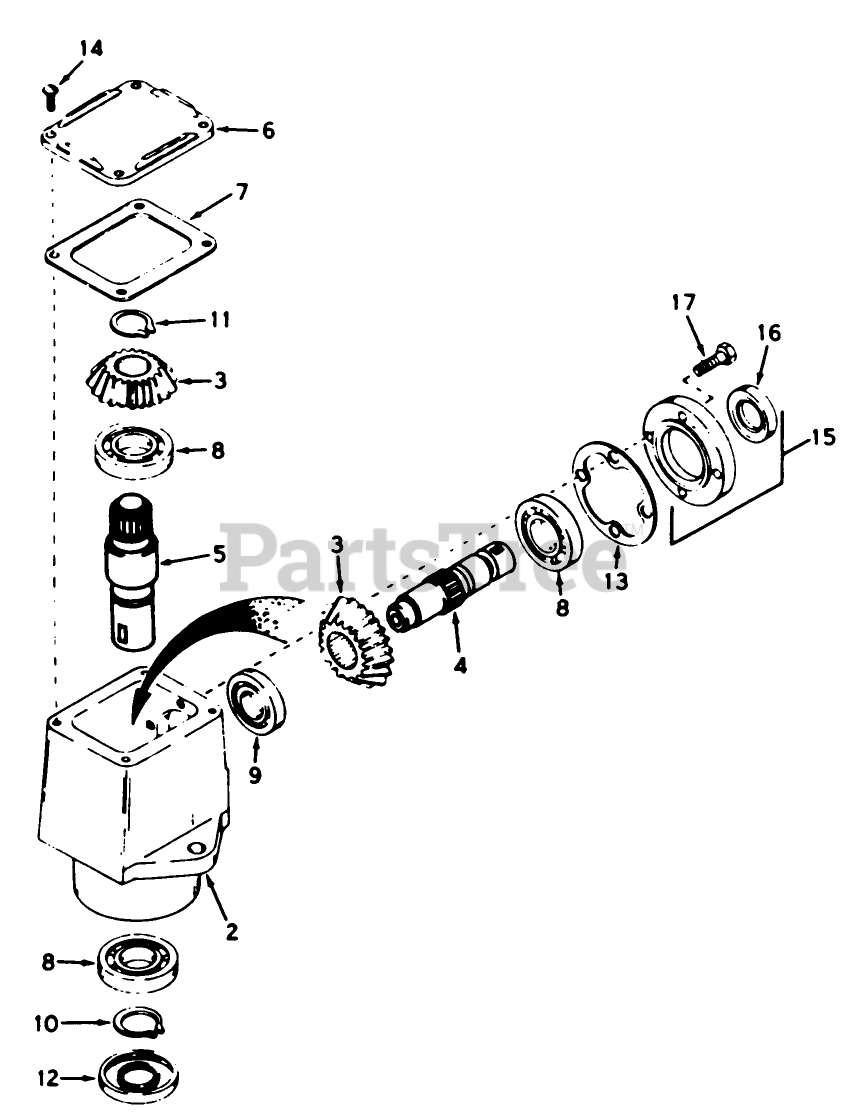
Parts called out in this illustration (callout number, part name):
2	Housing, Right Angle Drive
3	Bevel Gear
4	Shaft, Input
5	Shaft, Output
6	Cover
7	Gasket
8	Bearing
9	Bearing
10	Ring-Snap
11	Ring-Snap
12	Seal
13	Gasket
14	Screw
15	Cap and Seal Assembly, Retainer (Includes Nos. 16 17)
16	Oil Seal
17	Screw, Hex Hd., 1/4-10 x 1
